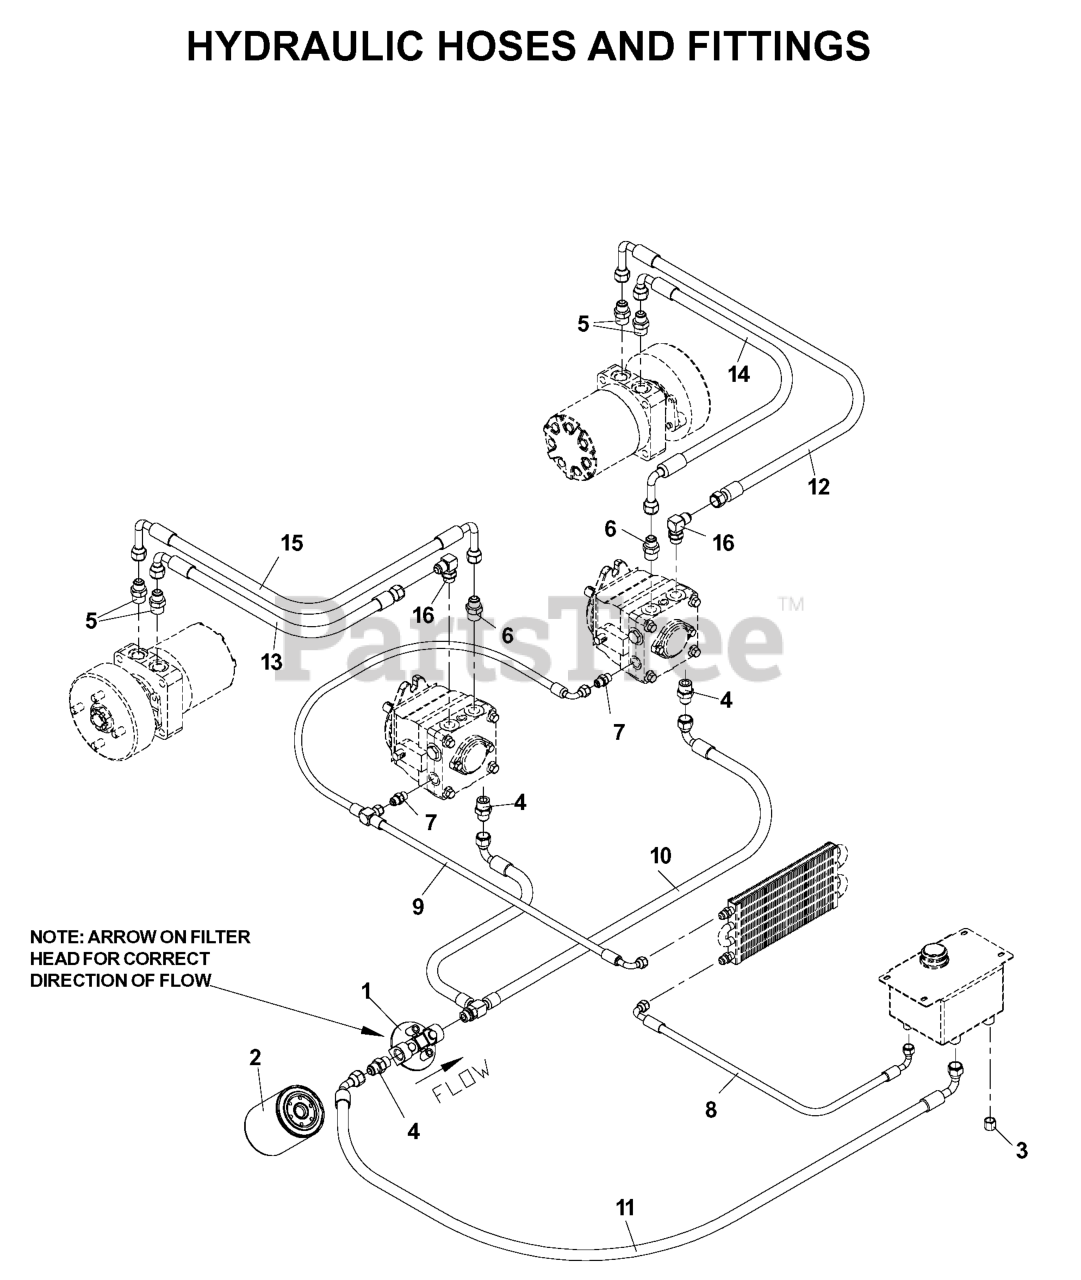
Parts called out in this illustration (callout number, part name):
1	FILTER HEAD
2	HYDRAULIC OIL FILTER
3	NUT 9/16-18 JIC CAP
4	FITTING, STRAIGHT F6400-8-8-0
